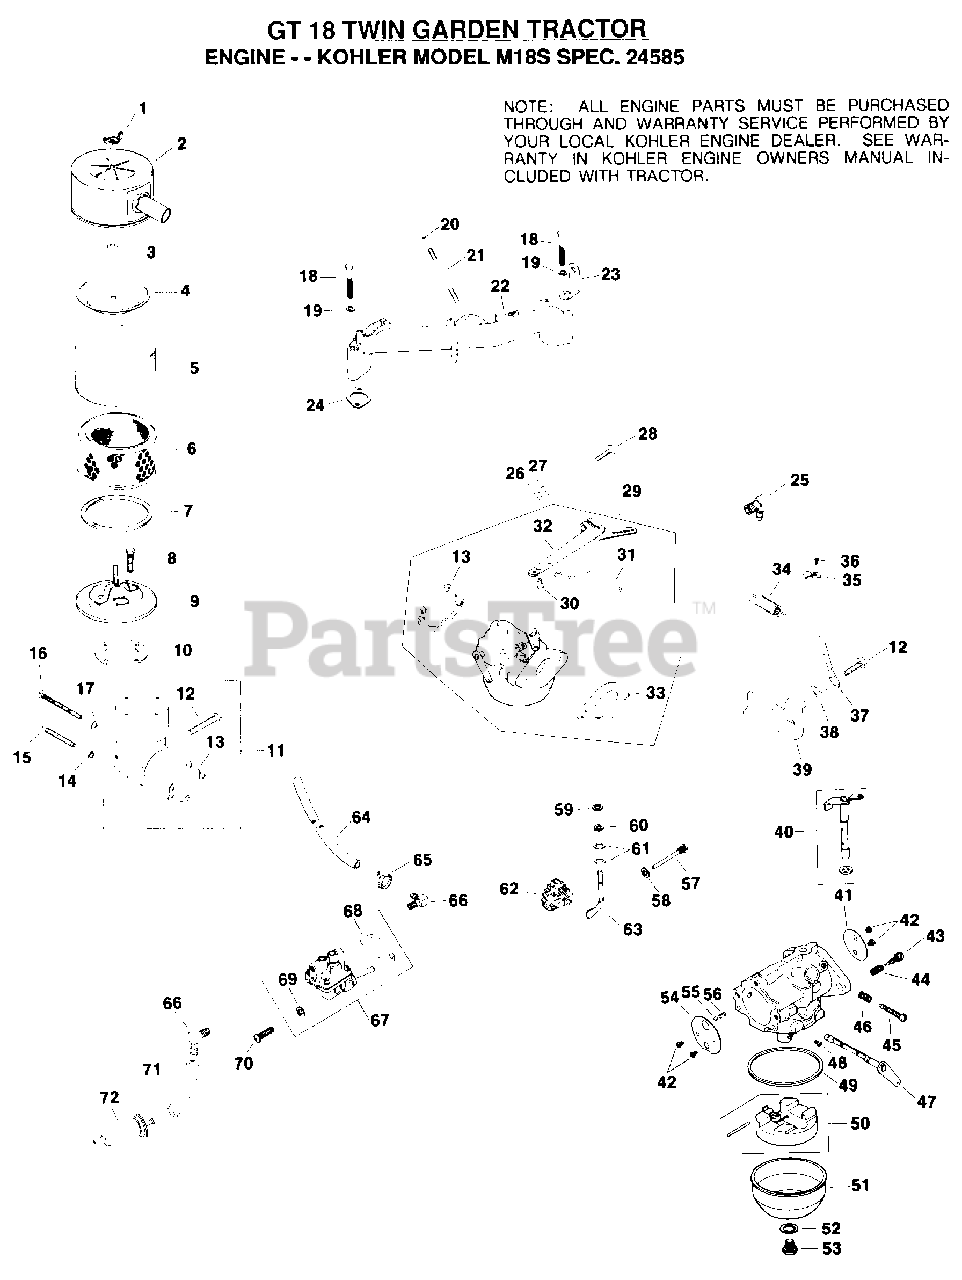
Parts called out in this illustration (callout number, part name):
1	WING NUT
2	COVER, AIR CLEANER
3	SEAL ELEMENT
4	COVER AIR CLEANER ELEMENT
7	SEAL
8	SCREW
10	GASKET
13	GASKET, AIR CLEANER
14	WASHER
15	SCREW
16	SCREW
17	WASHER
18	SCREW
19	WASHER
20	NUT
21	STUD
22	MANIFOLD, INTAKE
23	STRAP, LIFTING
26	NUT
27	WASHER
29	KIT, CARBURETOR
30	BUSHING, LINKAGE
31	LINK, GOVERNOR
32	ARM, GOVERNOR
33	GASKET
34	SPRING, GOVERNOR
35	CLAMP
36	SCREW
37	LEVER, SPEED CONTROL
38	STOP, GOVERNOR
39	STOP, HIGH SPEED
40	SHAFT, THROTTLE
53	SCREW, BOWL RETAINER
57	PIN
58	WASHER
59	WASHER, PLAIN 1/4
60	RETAINER
61	WASHER
65	CLAMP, HOSE
68	GASKET, FUEL PUMP
69	WASHER, PLAIN 1/4
